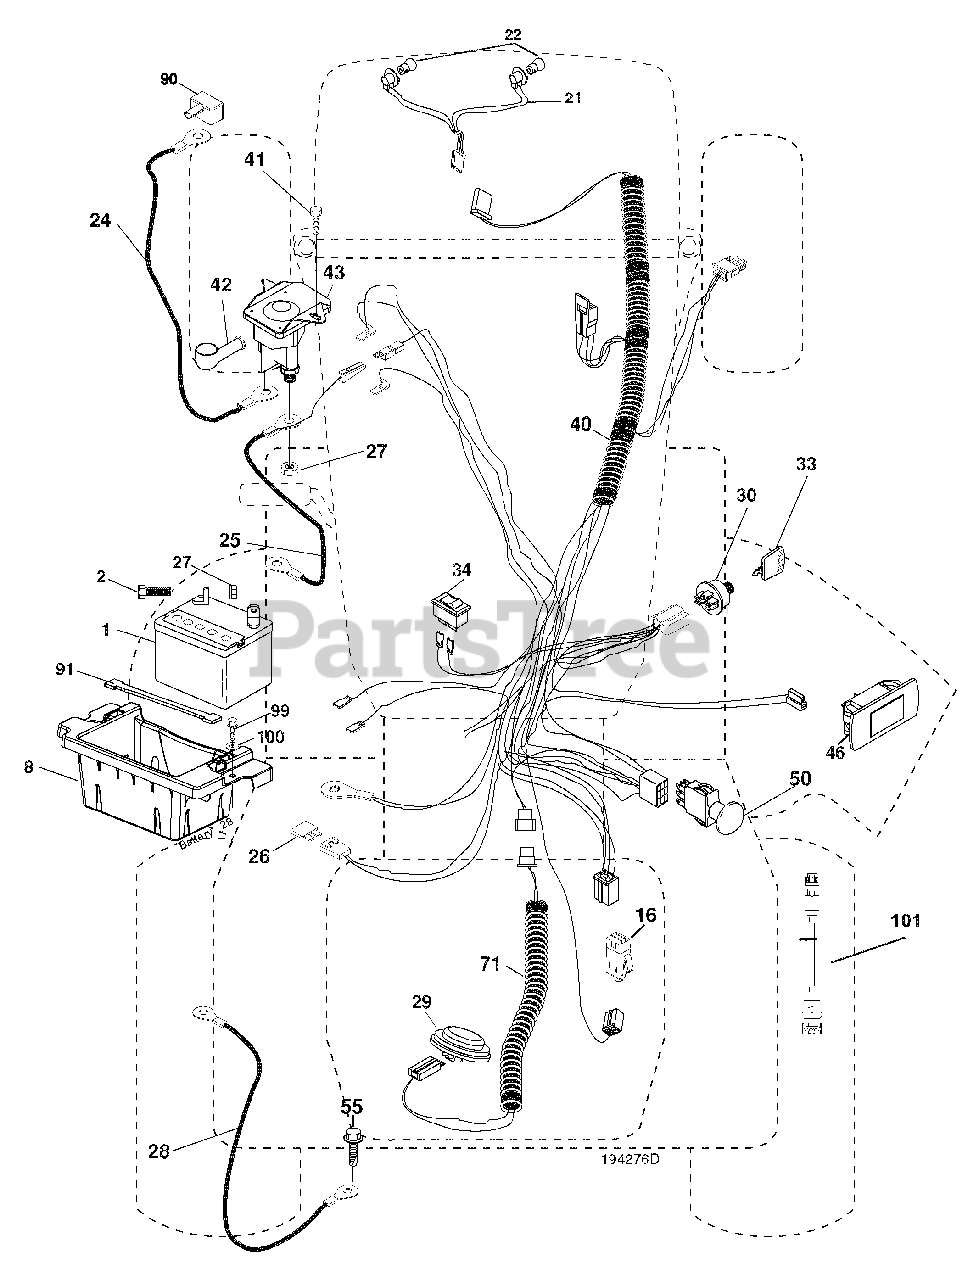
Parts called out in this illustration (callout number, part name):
1	Battery
2	Bolt Hex Head 1/4-20 x 3/4
8	Box Battery
16	Switch Interlock Push-In
21	Harness Socket Light W/4152J
22	Bulb Light
24	Cable Brty
25	Cable Starter
27	Nut Keps Hex 1/4-20 unc
28	Cable, Ground
29	Switch, Seat
30	Switch, Ign
33	Key, Ignition
34	Switch Light / Reset
40	Harness Ign.
41	Screw Thd Cut 1/4-20 x 1/2
42	Cover, Terminal
43	Solenoid
46	Gauge Servicereminder Hrmtr
50	Switch PTO
55	Screw Thdrol 5/16-18 x 3/4 TYTT
71	Harness Ign. Dash
90	Cover Terminal
91	Strap Battery Mount Front
99	Screw Hexwsh Thdrol 1/4-20 x 3/4
100	Washer 9/32 x 7/8 x 16 Ga.
101	Harness Pigtail ROS
